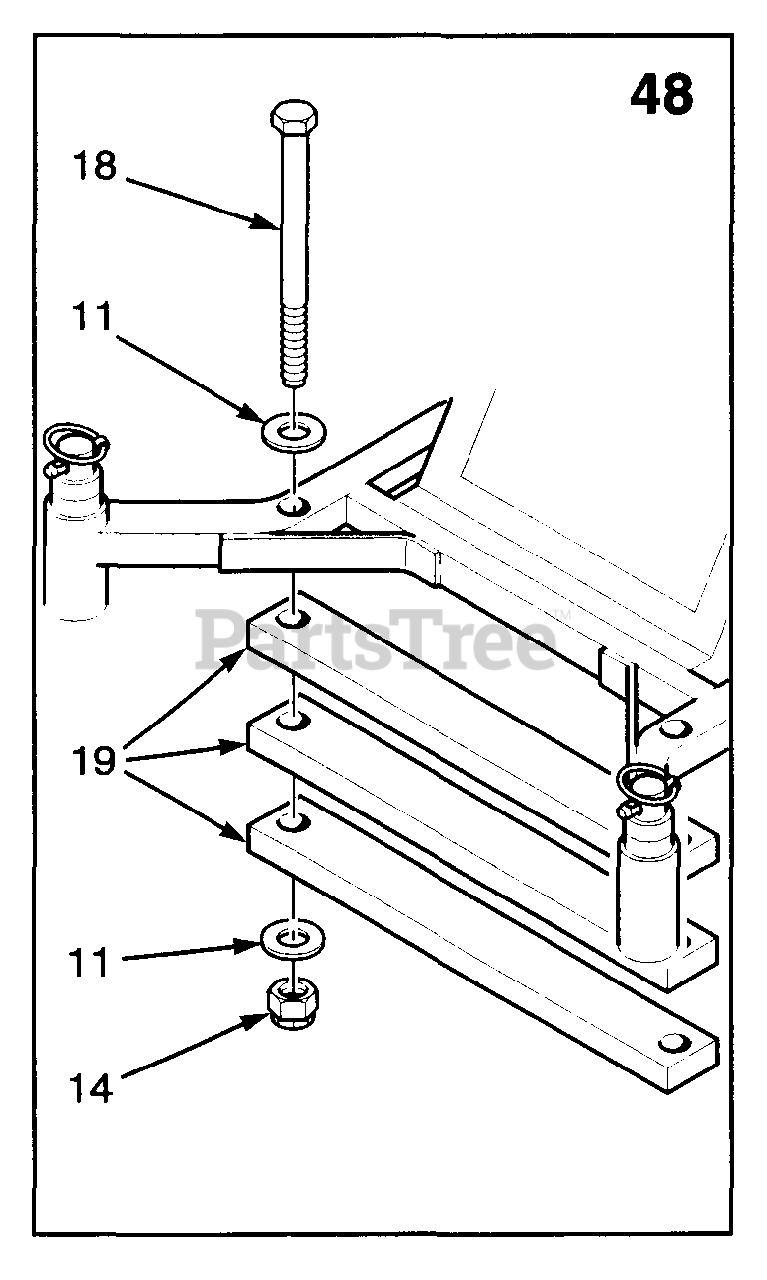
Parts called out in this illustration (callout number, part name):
11	Flat Washer, 3/8 (.391 x .938 x .105)
14	Nut, 3/8-16 Elastic Stop
18	Bolt, 3/8-16 x 6.00" Hex Head
18	Bolt, 3/8-16 x 5.00" Hex Head
19	Weight Bar
